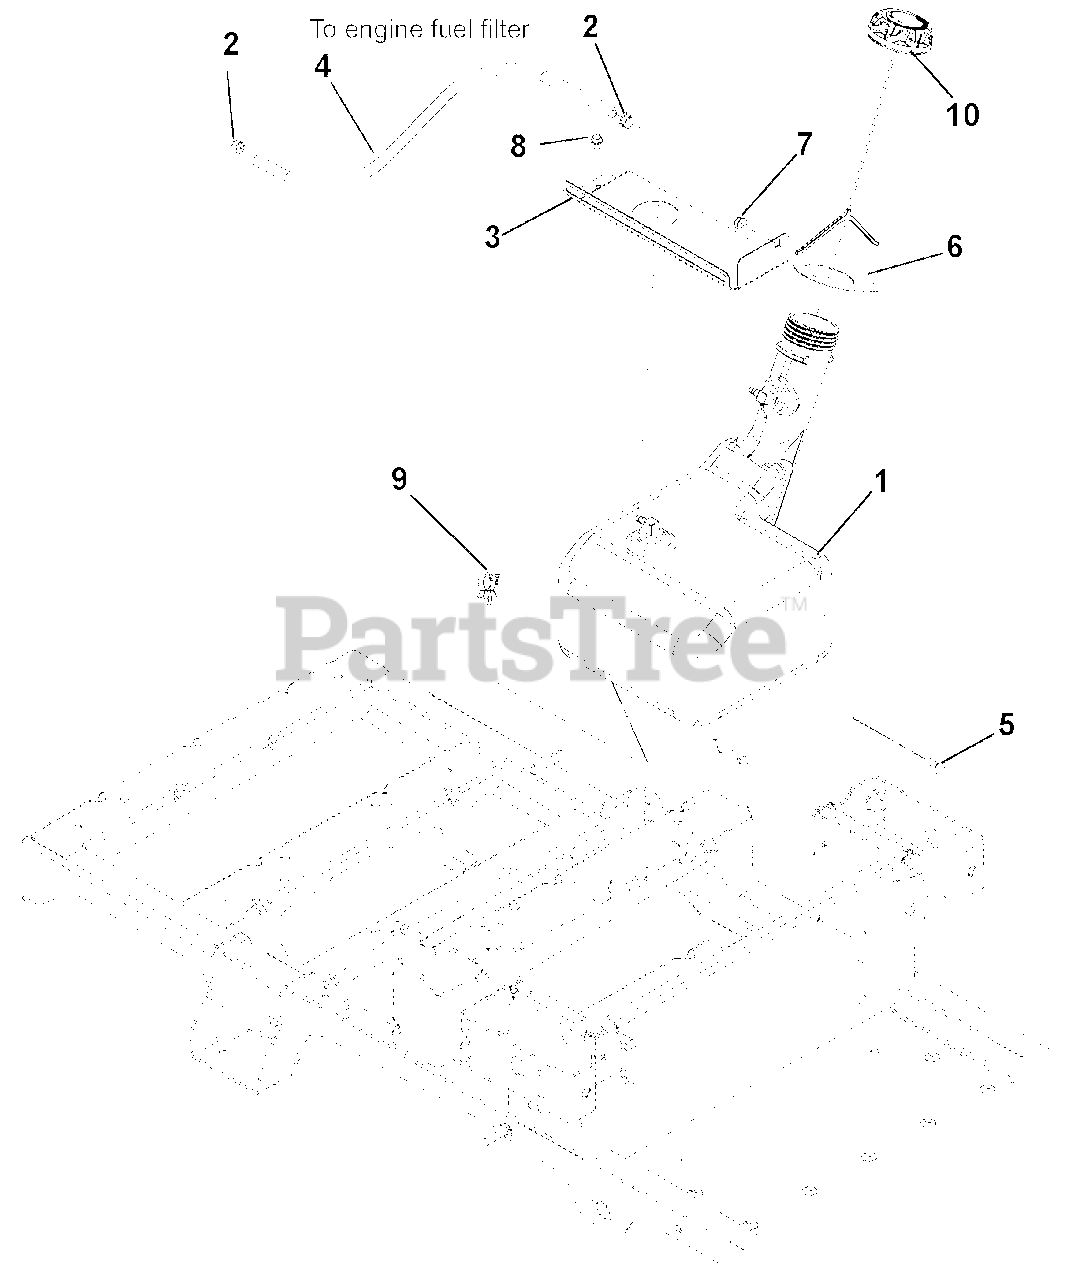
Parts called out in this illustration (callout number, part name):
1	Fuel Tank Subassembly
2	Clamp, Fuel Line
3	Bracket, Tank Strap
4	Hose, .25 Low Perm Gas (as required)
5	Bolt, Round Head Square Neck .25-20 x .75
6	Seal, Tank Neck
7	Nut, .25-20 Nyloc Flange
8	Screw, Tapping .25-20 x .50 Hex Washer Head
9	Wire Clip
10	Cap, Fuel Vent-In 2.25"
